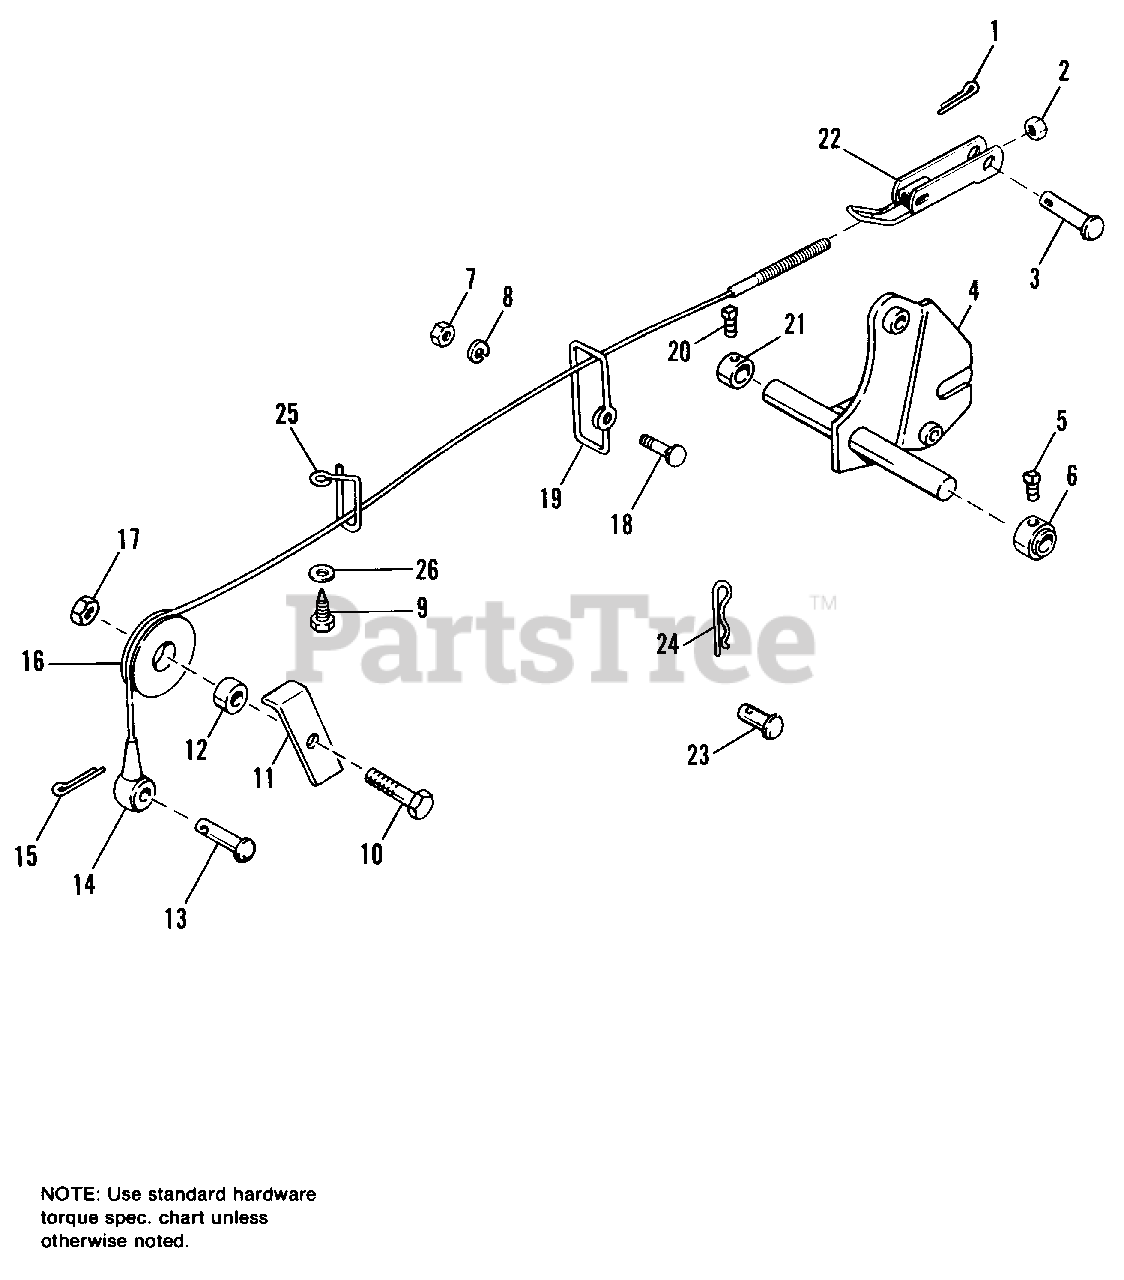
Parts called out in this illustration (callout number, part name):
1	COTTER PIN, 1/8 x 1
2	LOCKNUT, Hex, Jam, 3/8-24
4	LEVER ASSY., Lift
5	SETSCREW, Sq. Hd., 5/16-18 x 5/8
6	COLLAR, Set
7	NUT, Hex, Full, 5/16-18
8	LOCKWASHER, 5/16
9	SCREW, Hex Hd., Thread Forming Gimlet Pt., #14 x 1-1/4
10	CAPSCREW, Hex Hd., 3/8-16 x 1-1/4
11	GUARD, Cable
13	PIN
14	CABLE ASSY., Lift
15	COTTER PIN, 3/32 x 1
17	LOCKNUT, Hex, Jam, 3/8-16
18	CARRIAGE BOLT, 5/16-18 x 1
19	GUIDE, Cable
20	SETSCREW, Sq. Hd., 5/16-18 x 1/2
21	COLLAR, Set
22	CLEVIS ASSY., Lift
24	CLIP, Spring
25	RETAINER, Cable
26	WASHER, Plain
